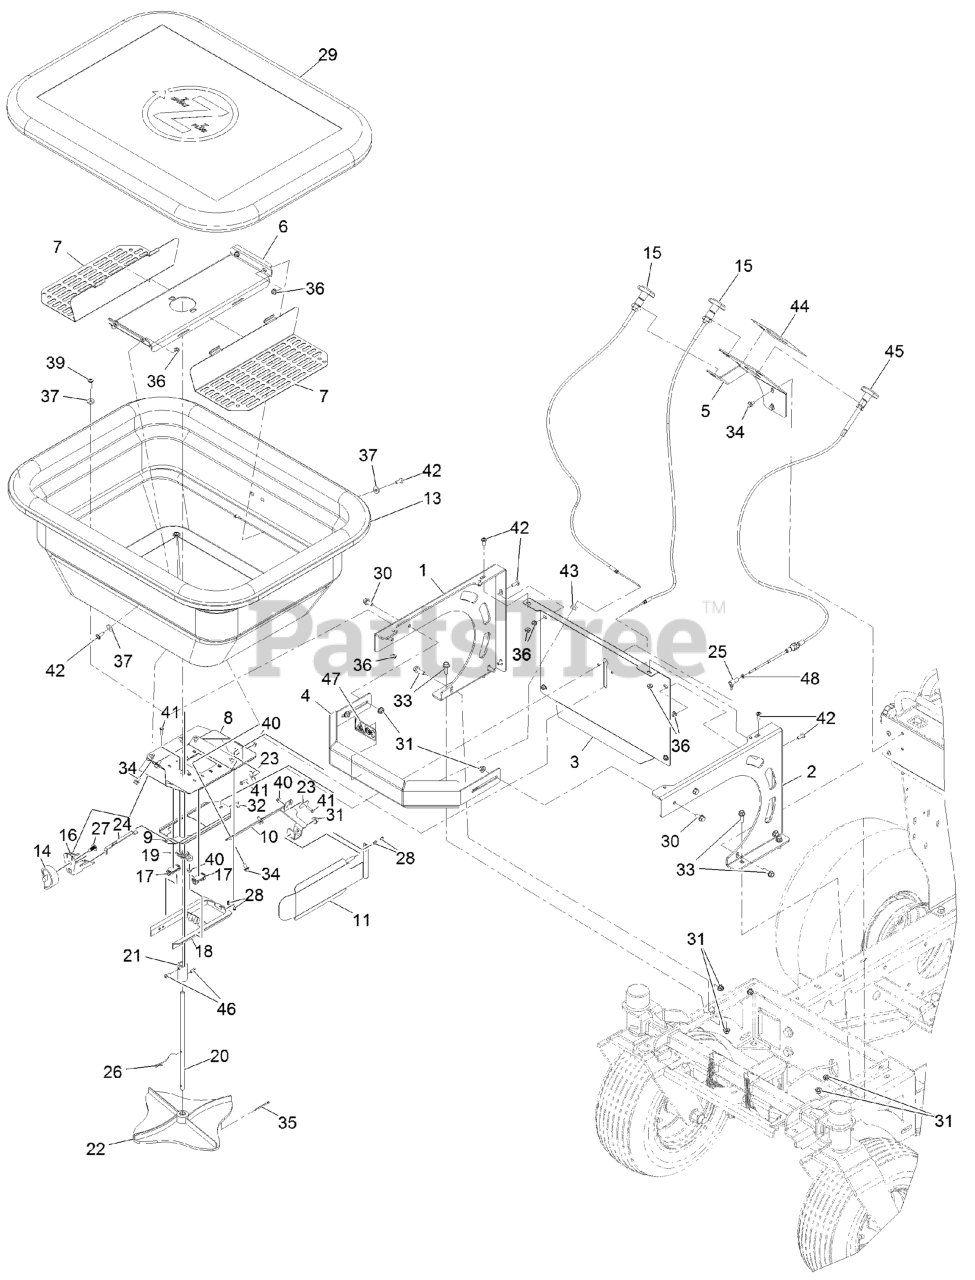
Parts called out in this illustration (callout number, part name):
1	Side-Hopper, Rt
2	Side-Hopper, Lt
3	Backshield-Hopper
4	BUMPER-FRONT, HOPPER
5	Mount-Speedometer
6	PAN-HOPPER, 220
7	SCREEN-HOPPER, 220
8	PLATE-BASE, HOPPER
9	Slide-Door, Hopper
10	Mount-Deflector, Side
11	Deflector-Side, Spreader
13	HOPPER-220LB
14	DIAL
15	CABLE-PUSH/PULL
16	MOUNT-DIAL
17	GUIDE-RATE, GATE
18	DIFFUSER
19	BEARING-FLANGE
20	SHAFT-HOPPER, 220
21	COUPLER-SS
22	SPINNER-SPREADER
23	RETAINER, CABLE
24	LINKAGE-GATE, RATE
25	BALL JOINT-SS
26	WIRE-AGITATOR
27	CLIP
28	RETAINER-CABLE, WIRE
29	COVER-HOPPER, LARGE
30	SCREW-HHF
31	Nut-Hex Flange
32	Nut,NYL Lock,#10-32,ST/ST 18-8
33	SCREW-HHF
34	SCREW-HHF
35	PIN-COTTER
36	Nut-Hex Flange
39	Screw-Hsbhf
40	Nut-Hex Flange
41	SCREW-HH
42	Screw-Hsbhf
43	Grommet-Rubber
44	DECAL-HOPPER CONTROL
45	CABLE-PUSH/PULL
46	Screw-SQH
47	Decal-Dismemberment Hazard
48	Nut,Hex Jam Mch Scr,10-32,Sst
